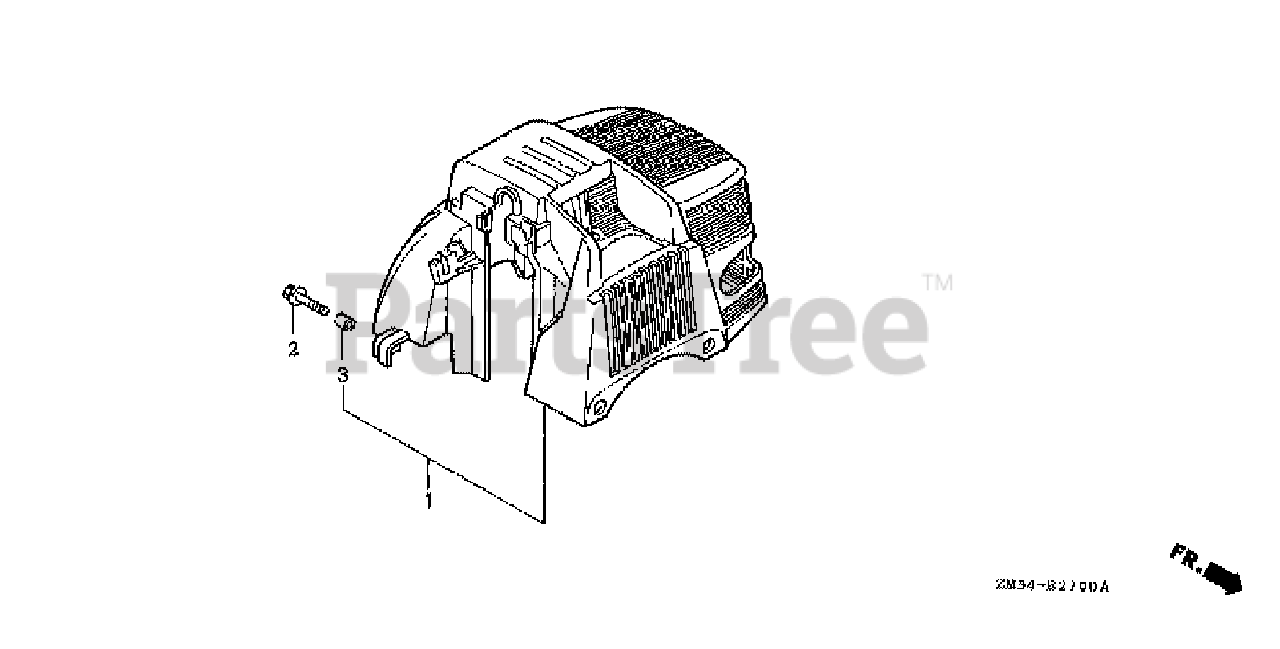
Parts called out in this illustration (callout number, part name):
1	COVER COMP., TOP *R8* (BRIGHT RED)
2	BOLT, FLANGE (5X22)
3	COLLAR, TOP COVER
